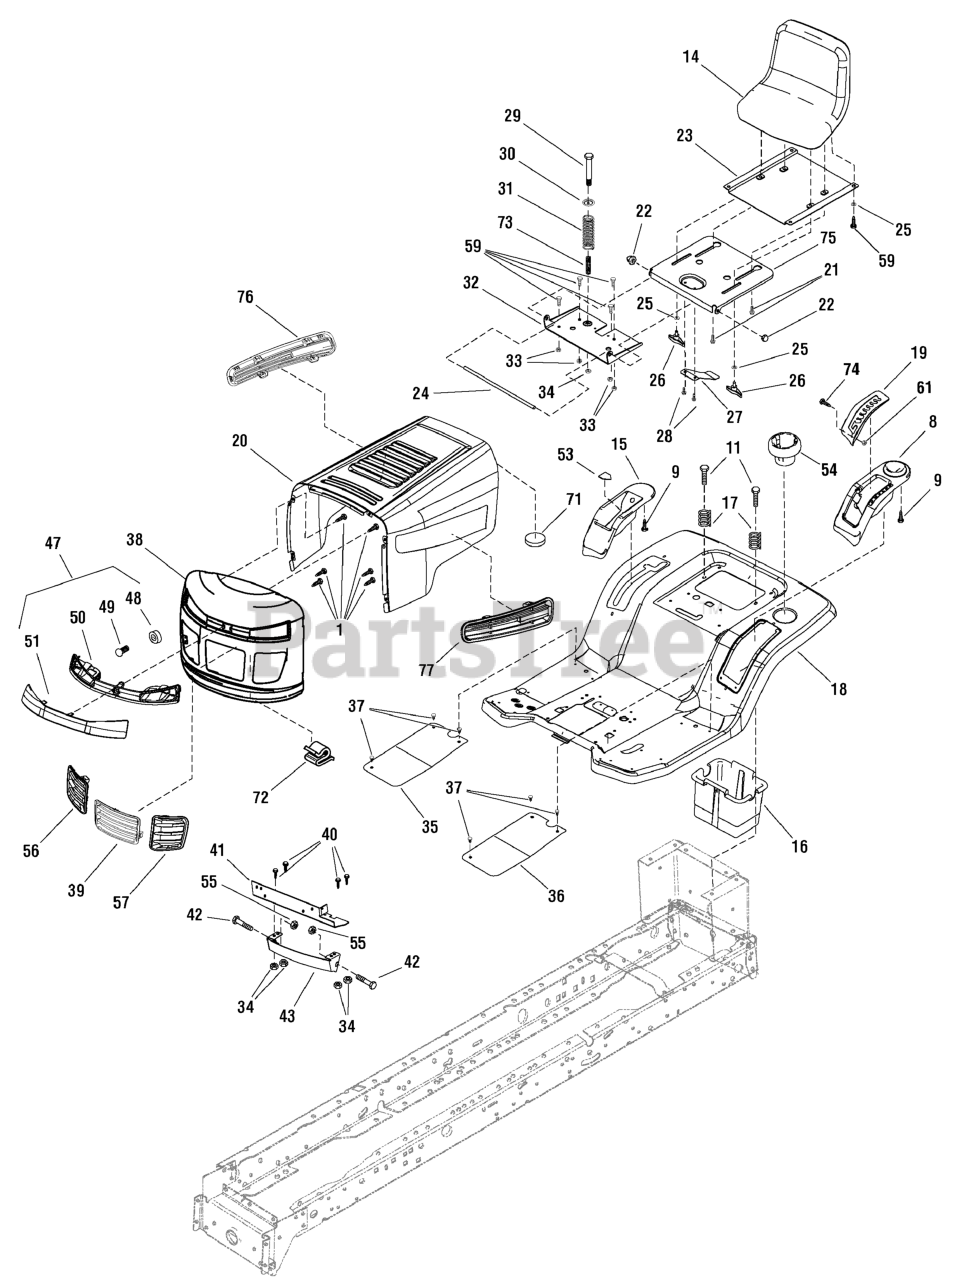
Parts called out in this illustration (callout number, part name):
1	SCREW, Thread Forming
8	POD, With Cup Holder
9	SCREW, Thread Cutting, 1/4-20
11	CAPSCREW, 5/16-18 x 3/4
14	SEAT, High Back
14	SEAT, Low Back
15	POD, With Compartment
16	CONTAINER, Battery
17	SPRING, Compression
18	DECK, Seat
19	PLATE, Index
20	HOOD
21	BOLT, Shoulder 5/16-18 x 5/8
22	CAP, Push On
23	SEAT PLATE
24	ROD, Pivot
25	WASHER, Flat, 5/16
26	BOLT, Wing 5/16-18 x 1/2
27	LEAF SPRING
28	SCREW, 1/4-14 x 3/8
29	BOLT, Shoulder 1/4-20 x 5/16
30	WASHER, Cup
31	SPRING, Compression
32	BRACKET, Seat Pivot
33	NUT, Nylock 5/16-18
34	NUT, Hex Flange Lock, 1/4-20
35	MAT, Right
35	MAT, Molded Right
36	MAT, Left
36	MAT, Molded Left
37	FASTENER, Panel
38	GRILLE
39	INSERT, Center Grille
40	SCREW, 1/4-20 x 5/8
41	BRACKET, Support
42	BOLT, Shoulder
43	BRACKET, Lower Pivot
47	HEADLIGHT ASSEMBLY
48	SOCKET, Lamp
49	BULB, Light
49	BULB, 12.8V
50	HOUSING, Light
51	LENS, Light
53	INDICATOR, Cutting Height
54	HOLDER, Cup
55	NUT, Centerlock, 3/8-16
56	INSERT, Right Grille
57	INSERT, Left Grille
59	BOLT, Hex, 5/16-18 x 5/8
61	NUT, Flange Lock 1/4-20
73	SPRING, Brake Compression
74	SCREW, Shoulder #10-24
75	SUPPORT, Seat
76	INSERT, Right Hood
77	INSERT, Left Hood
